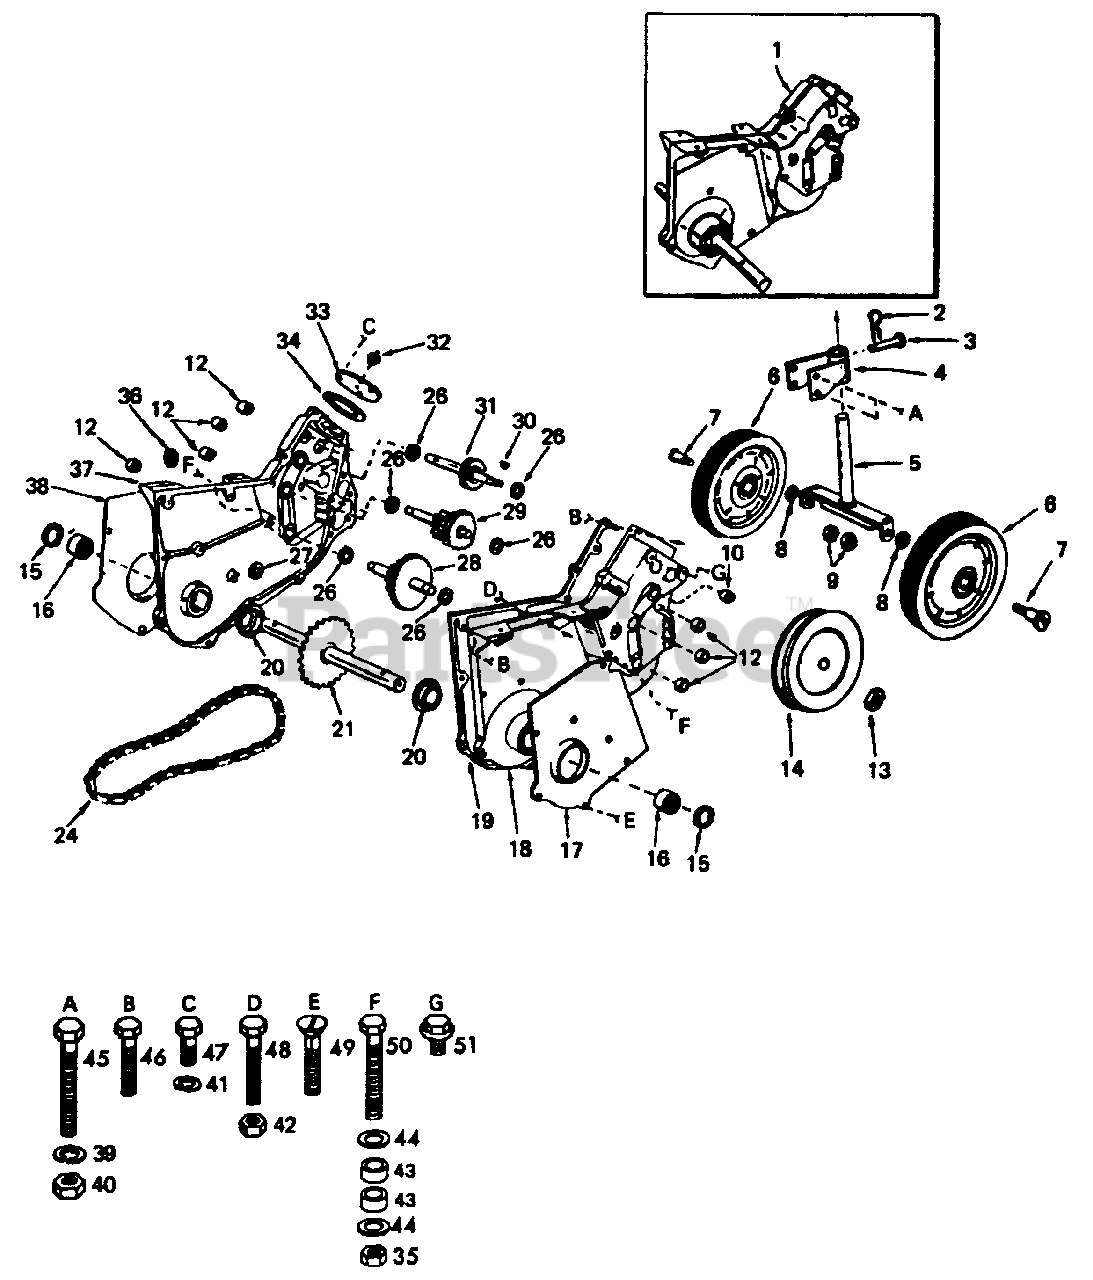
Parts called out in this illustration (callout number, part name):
1	Transmission
2	Retainer Spring
3	Drilled Pan Head Rivet 3/8 x 1-3/4
4	Gauge Wheel Sleeve and Brackets
5	Gauge Wheel Adjusting Shaft and Bracket
7	Shoulder Bolt
8	Washer 13/32 x 13/16 x 11 Ga.
9	Locknut 3/8-16 UNC Nylock
10	Needle Bearing
12	Needle Bearing
13	Locknut 1/2-20 UNF
14	Input Sheave
15	Oil Seal
16	Needle Bearing
17	Gear Case Shield L.H.
18	Gear Case and Bearings L.H. Half
20	Thrust Cap
21	Tine Shaft and Sprocket
24	Roller Chain
26	Thrust Washer
28	2nd Reduction Shaft and Gears
29	1 st Reduction Shaft and Gears
30	Woodruff Key. 3/16 x 5/8
31	Input Shaft and Pinion
32	Relief Valve
33	Gear Shift Cover
34	Gasket
35	Locknut 5/16-18 UNC
36	Pipe Plug 1/2-14 N.P.T.
37	Gear Case and Bearings R.H. Half
38	Gear Case Shield R.H.
39	Washer Lock 3/8
40	Hex Nut 3/8-16 UNC
41	Washer Lock, Hvy. Hel. Spring
42	Hex Nut 5/16-18 UNC
44	Washer 11/32 x 11/16 x 16 Ga.
45	Hex Bolt 3/8-16 x 2-1/4
46	Hex Hd. Roll-Lok Thd. Forming Screw 5/16-18 x 1-1 /2
47	Hex Bolt 5/16-18 x 3/4
48	Hex Bolt 5/16-18 x 2
49	Flat Hd. Slotted Roll-Lok Thd. Forming Screws 5/16-18 x 3/4
50	Hex Bolt 5/16-18 x 6 Gr. 5
51	Screw Mach. Hex Hd. 5/16-18 x 3/4
